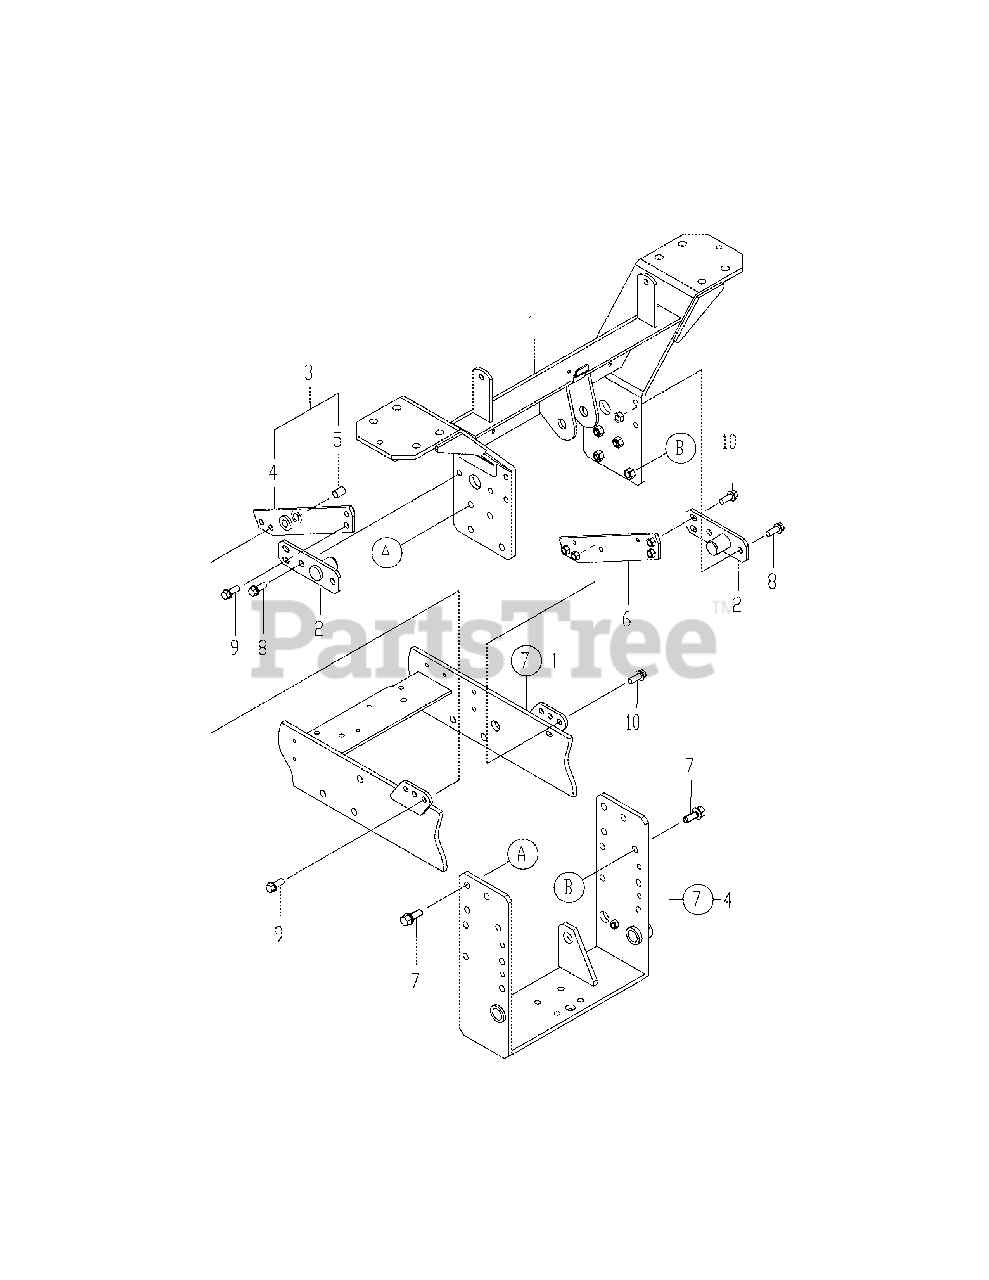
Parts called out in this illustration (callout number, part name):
1	Lower Frame Cmp
2	Plate, Side Cmp
3	Frame L, Joint Assy
4	Frame L, Joint Cmp
5	Bearing, 12 X 20
6	Frame R, Joint Cmp
